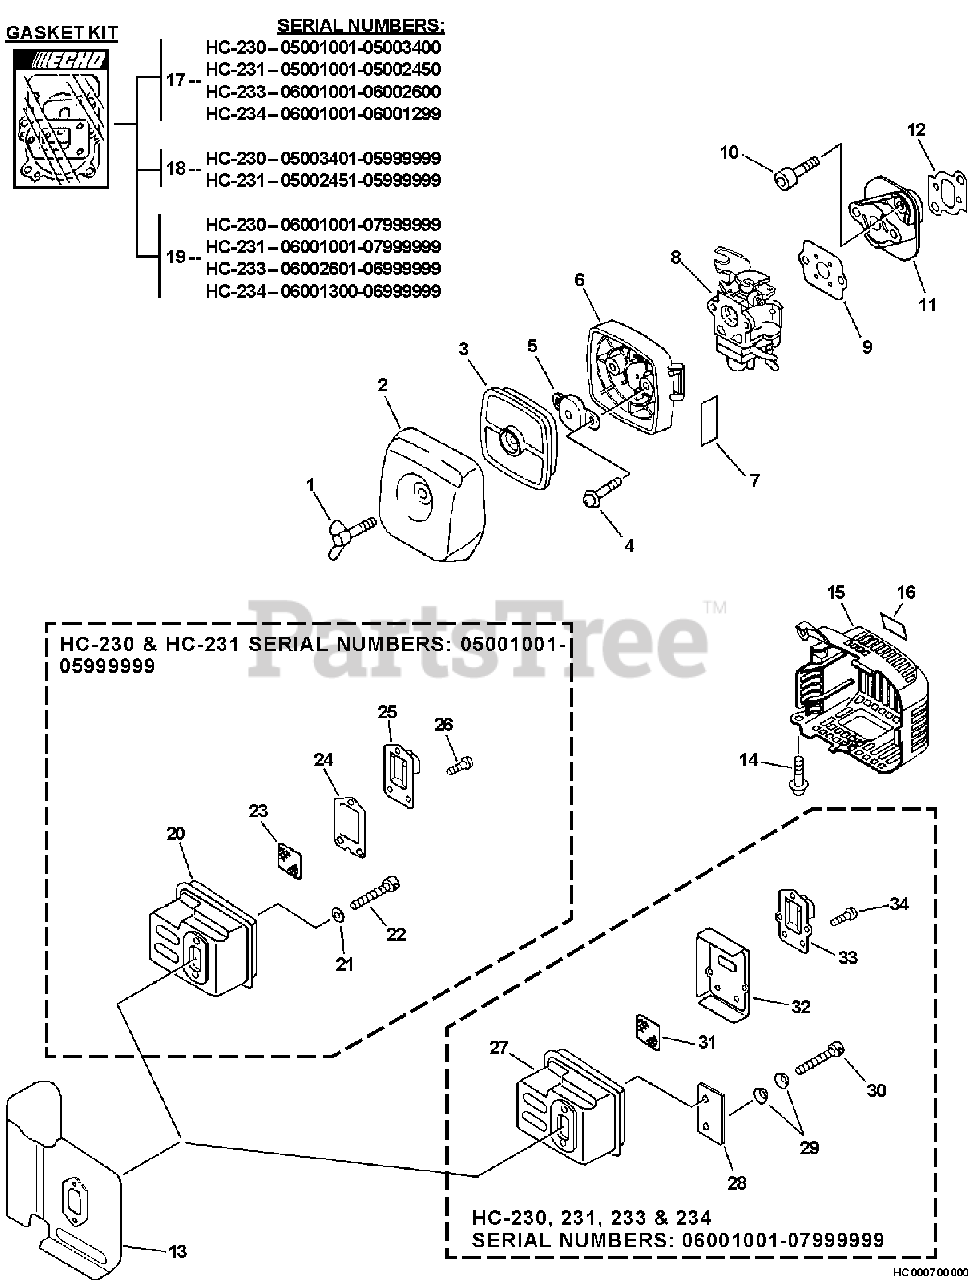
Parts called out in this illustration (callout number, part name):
1	THUMBSCREW
2	COVER, AIR FILTER - GRAY
3	FILTER, AIR - SINGLE LAYER
4	SCREW - 5X60
5	PLATE, PREVENT
6	CASE, AIR FILTER - GRAY
7	LABEL - CHOKE
8	CARBURETOR WYJ-314
9	GASKET, INTAKE
10	SCREW - 5X25
11	INSULATOR, INTAKE
12	GASKET, INTAKE
13	SHIELD, EXHAUST
14	SCREW - 5X12
15	COVER, EXHAUST
16	LABEL - HOT SURFACE
17	GASKET KIT
18	GASKET KIT
19	GASKET KIT
21	WASHER - 5
22	SCREW - 5X55
23	SCREEN, SPARK ARRESTOR
24	GASKET, EXHAUST
25	GUIDE, EXHAUST
26	SCREW - 4X10
27	MUFFLER
29	WASHER - CONICAL
30	SCREW - 5X55
31	SCREEN, SPARK ARRESTOR
32	GASKET, EXHAUST
33	GUIDE, EXHAUST
34	SCREW - 4X10
